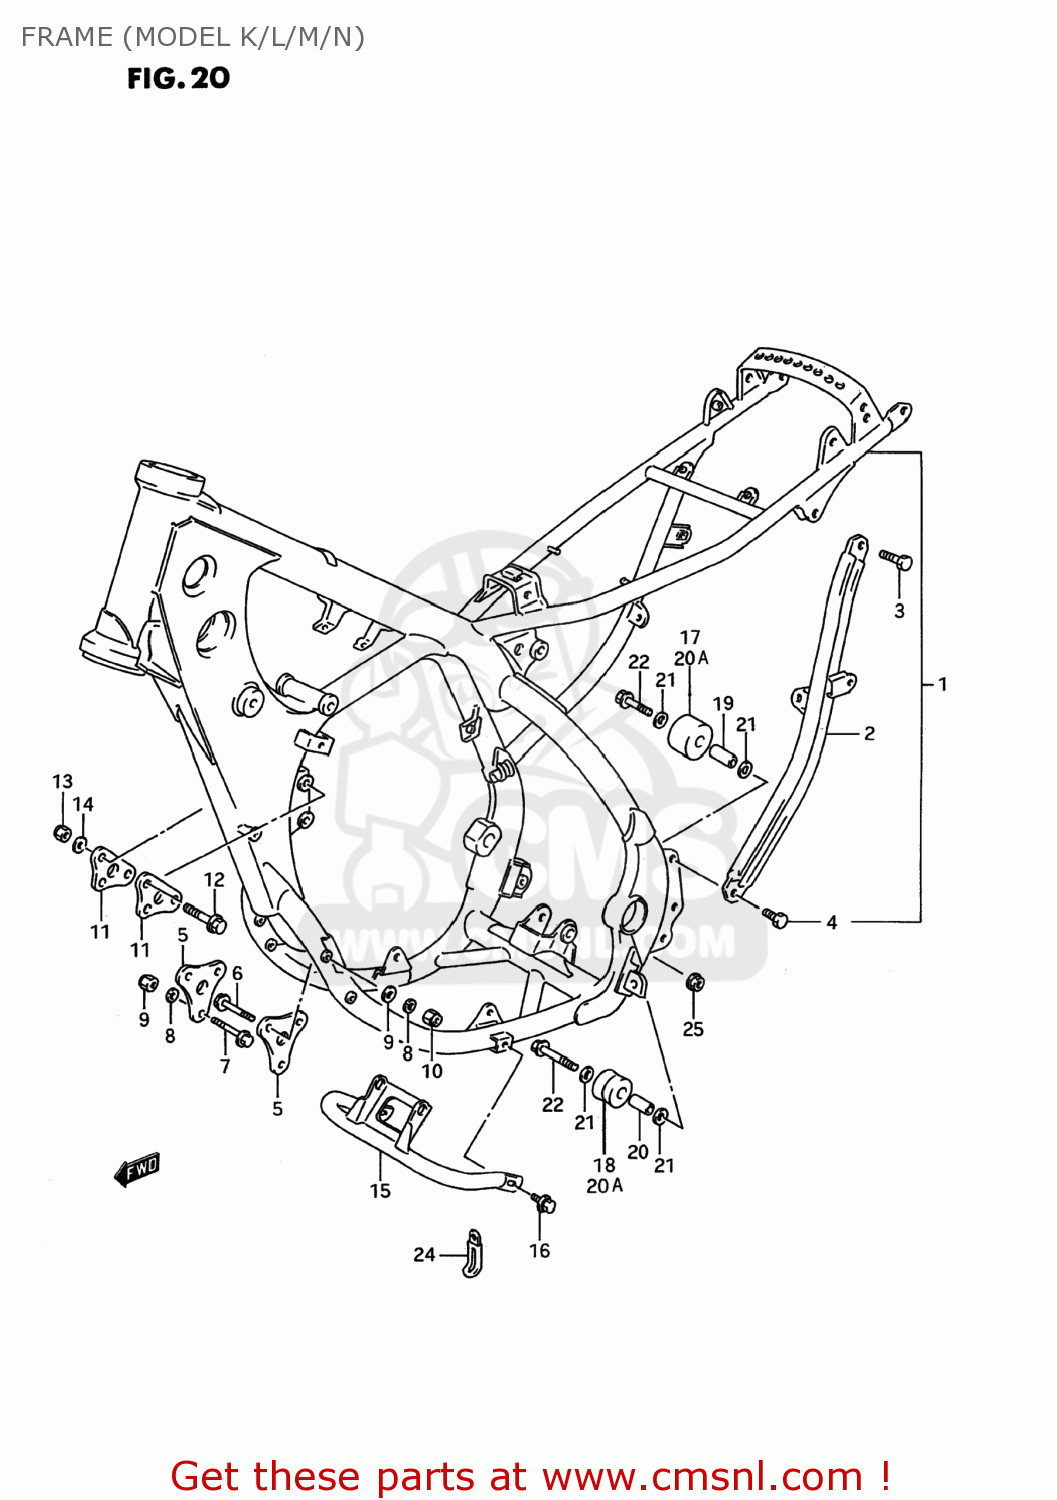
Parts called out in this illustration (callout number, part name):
1	FRAME SET
2	TUBE,FRAME SIDE,L
3	BOLT
4	BOLT
5	PLATE,ENG MTG FR
6	BOLT 8X55
7	BOLT M8X65
8	WASHER,LOCK
9	WASHER
10	NUT
11	PLATE,ENGINE MOUNT UPR
12	BOLT
13	NUT
14	WASHER
15	PROTECTOR,ENGINE
16	BOLT
17	ROLLER,CHAIN CONTROL
18	ROLLER,CHAIN CONTROL
19	SPACER (8.6X13.8X28)
20	SPACER(8.6X12X25.5)
20A	ROLLER,CHAIN
21	WASHER
22	BOLT(8X41)
23	BOLT(8X45)
24	CLAMP
25	NUT
